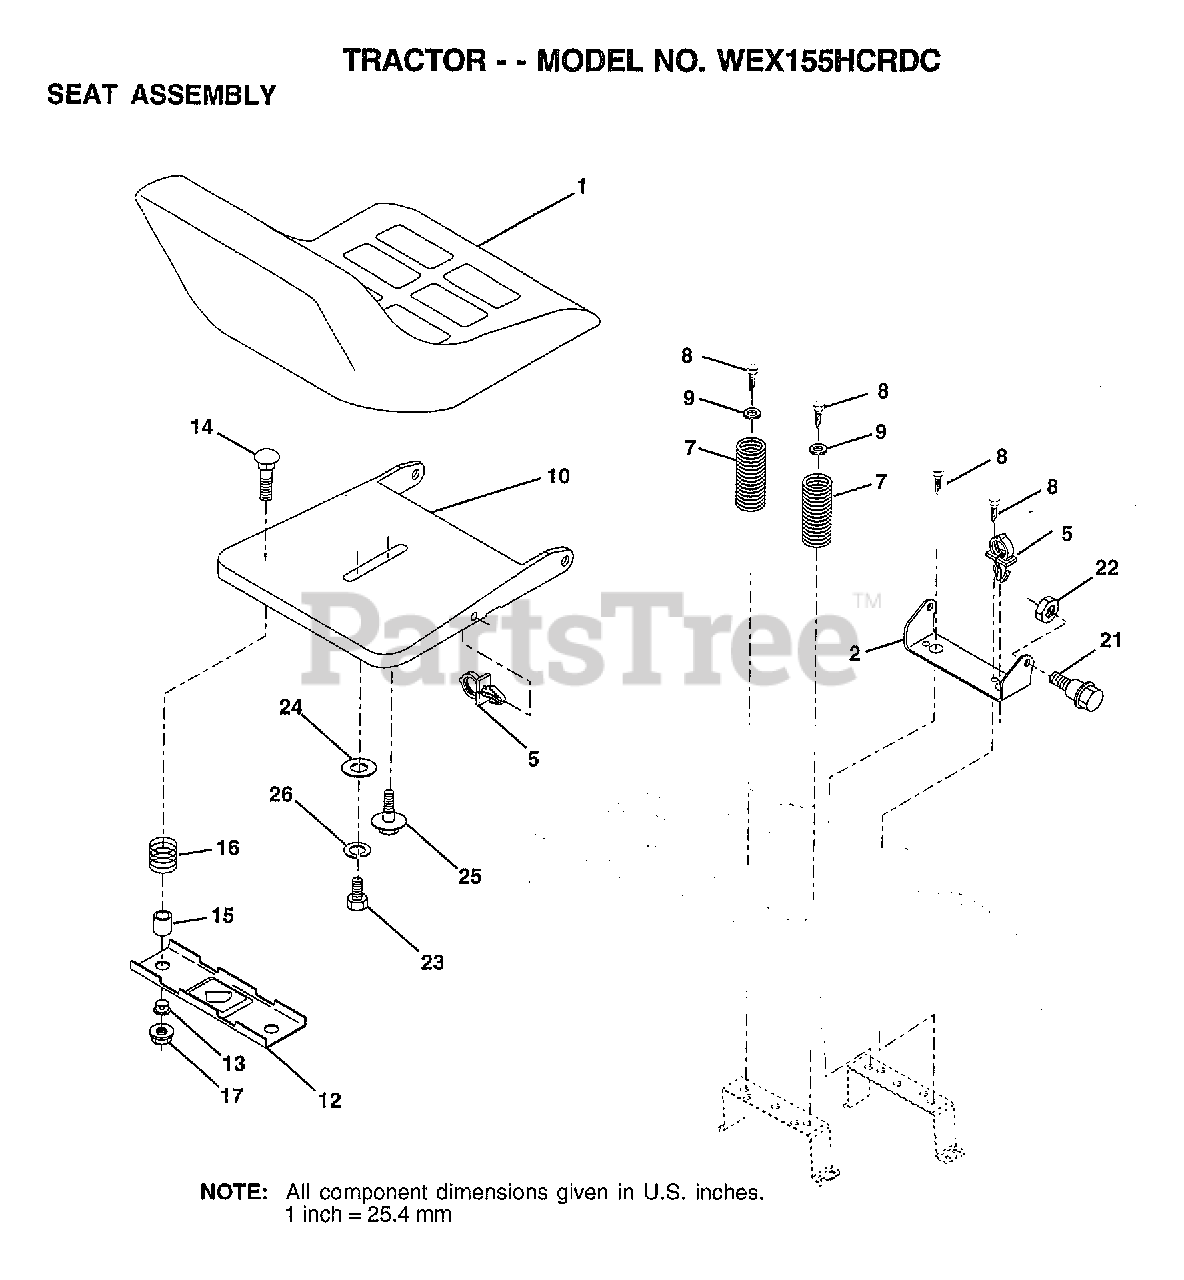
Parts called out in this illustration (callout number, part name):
2	BRACKET PVT SEAT
5	CLIP.PUSH-IN.HING
7	SPRING COMPRESSIO
8	SCREW
9	WASHER
10	PAN-SEAT
12	BRKT SWITCH
13	BUSHING
14	BOLT-RD HD SQ NK
15	SPACER SPLIT
16	SPRING COMPRESSED
21	BOLT
22	NUT
23	BOLT
24	WASHER
25	"BOLT,SHOULDER"
26	LOCKWASHER
